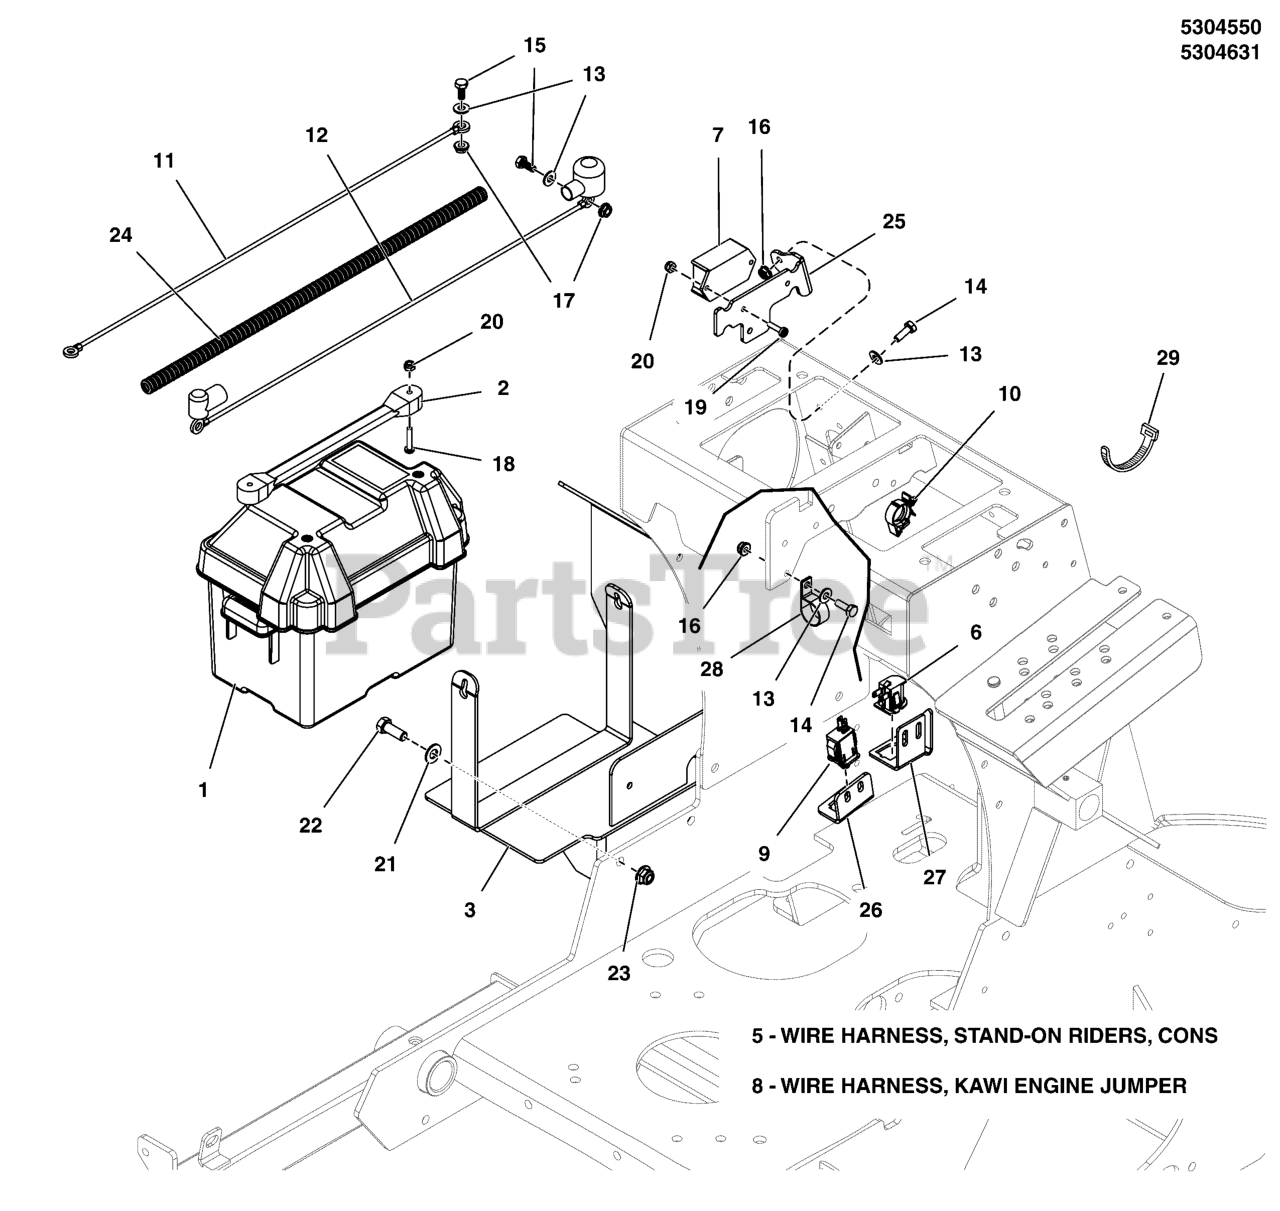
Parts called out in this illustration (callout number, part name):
1	BATTERY BOX, W/ DRAIN HOLE
2	STRAP, RUBBER
3	WELD, BATTERY MNT, SRSZ1 - RED
4	BATTERY, 11U1L, 350 CCA
5	WIRE HARNESS, SRS CONSOLIDATED
5	HARNESS, Wiring, Stand-On ZTR
6	SWITCH, SEAT
6	SWITCH, Push Button, NO, Black
7	MODULE, TIME DELAY, NO DIODE
8	WIRE HARNESS, JUMPER, KAWI
9	SWITCH, PLUNGER, NO, SINGLE POLE, SNAP-IN
10	ROSEBUD LOOM CLIP
11	BATTERY CABLE, NEG, 22, 1/4-5/16
12	BATTERY CABLE, POS, 22, 1/4-5/16
13	WASHER, 1/4 SAE
14	BOLT, 1/4"-20 X 3/4" GD5 YZ
15	HHCS, 1/4-20 X 0.625, GR5, ZINC/CLEAR
16	NUT, 1/4-20 Hex Nylock Flange
17	NUT, 1/4-20 HEX SERR. FLANGE
18	SCREW, #10-24 X 1 RS, CZ
19	SCREW, #10-24 X 3/4" ROUND PHILLIPS
20	NUT, Hex, Nylon Lock, #10-24
21	WASHER, 3/8 SAE
22	BOLT, 3/8-16 X 1" GD5 CZ
23	NUT, 3/8 - 16 HEX NYLOCK FLANGE
24	WIRE LOOM, 3/8 ID X 19 IN
25	PLATE, WIRE GUIDE / TDM MOUNT - BLK
26	Refer to: Parking Brake Group
27	Refer to: Operator Compartment Group
28	CLAMP, VINYL INSULATED, 1.00
29	TIE, SELF-LOCKING, 12"
